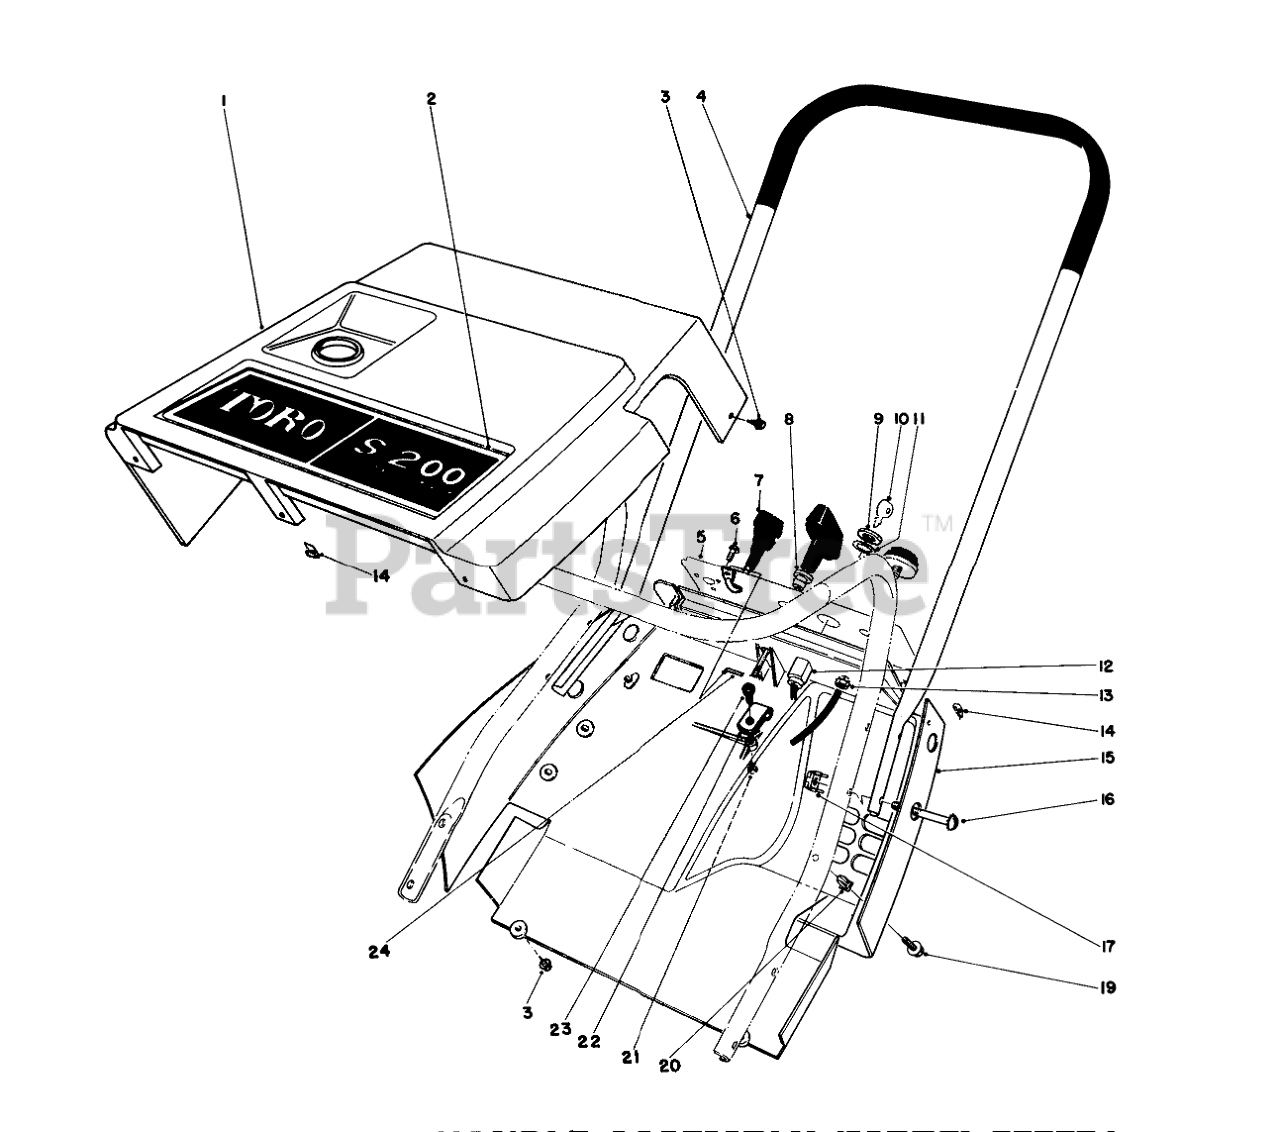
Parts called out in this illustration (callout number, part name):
1	Shroud-Upper
2	Decal-Toro
3	SCREW-HWHTF
4	Upper Handle
5	Decal-Control Panel
6	SCREW-PLASTITE
7	CHOKE CONTROL ASM
8	GUIDE-ROPE, STARTER
9	NUT-HH
10	Key
11	WASHER-TOOTH, INTERNAL
12	SWITCH
13	NUT-KEPS
14	NUT-TYPE J
15	Lower Shroud
16	Sems Mach. Screw
17	TINNERMAN NUT
19	SCREW-HWHTF
20	Push Nut
21	NUT-LOCK, NI
22	CABLE CLAMP
23	SCREW-SHWH
24	CONTROL WIRE
